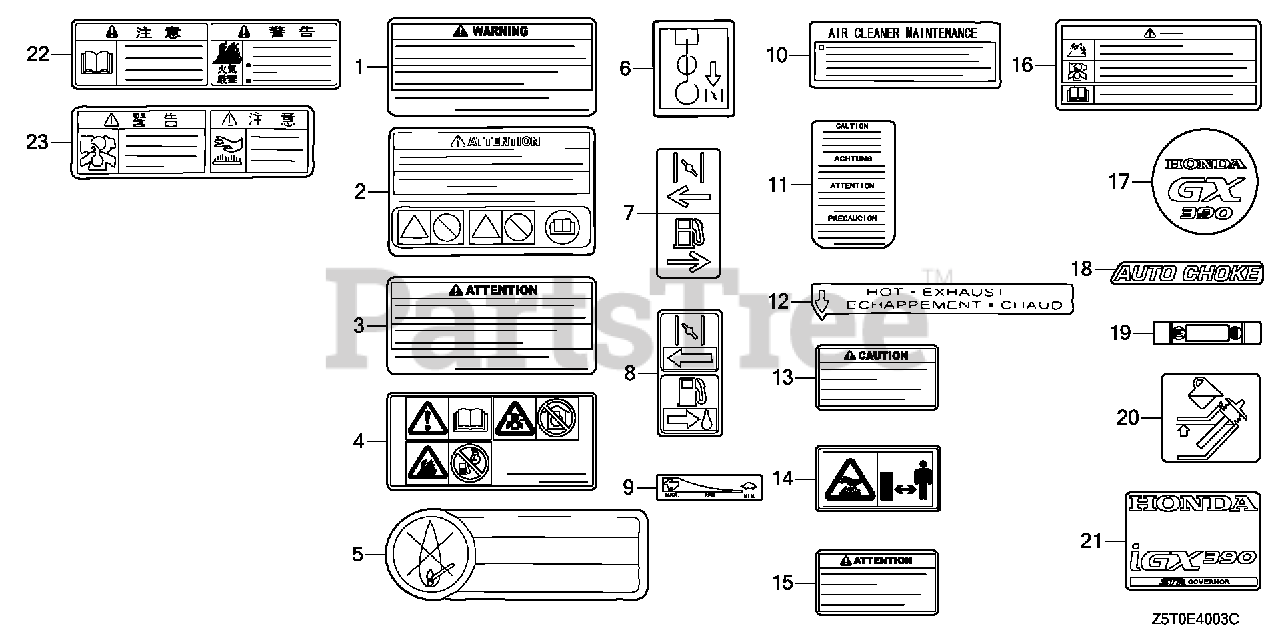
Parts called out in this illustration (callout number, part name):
1	MARK, OPERATOR CAUTION (ENGLISH)(MADE IN THAI)
3	MARK, OPERATOR CAUTION (FRENCH)(MADE IN THAI)
6	MARK, CHOKE
10	MARK, AIR CLEANER (ENGLISH)
